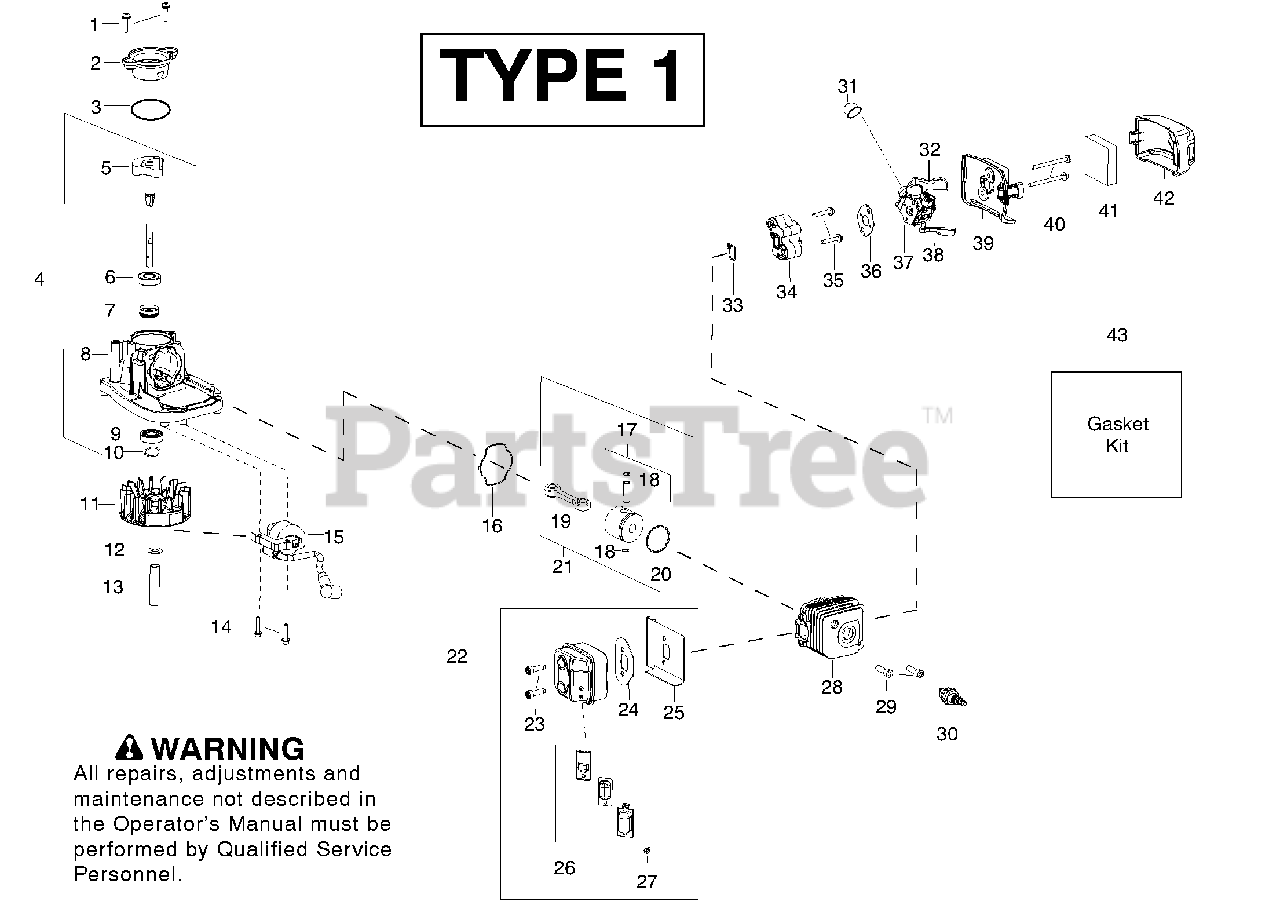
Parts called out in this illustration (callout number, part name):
2	Assy - Rear Plug
3	O-Ring - Rear Plug (kit)
4	Kit - Crankshaft / Crankcase
5	Assy - Crankshaft
6	Bearing - Inner
7	Seal - Crankshaft
8	Assy - Crankcase
9	Bearing - Outer
10	Ring - Crankshaft Retainer
11	Assy - Flywheel
13	Spacer - Flywheel
15	Module - Ignition
16	Seal - Crankcase / Cylinder (kit)
17	Kit - Piston
18	Retainer - Wrist Pin
19	Kit - Connecting Rod
20	Ring - Piston
21	Kit - Piston and Rod
22	Kit - Muffler
23	Screw - Muffler
24	Gasket - Muffler (kit)
25	Shield - Muffler
26	Kit - Spark Arrestor
27	Screw
28	Cylinder - Machined (25cc)
29	Screw - Cylinder
30	Accy - Spark Plug (RCJ-6Y)
31	Bulb - Purge
32	Kit - Throttle
33	Seal - Cylinder/Carb. Adapter (kit)
34	Adapter - Carburetor
36	Gasket - Carburetor (kit)
37	Kit - Carburetor Assy.
38	Kit - Choke
39	Base - Air Box
41	Filter - Foam Air
42	Cover - Air Box
43	Kit - Gasket
